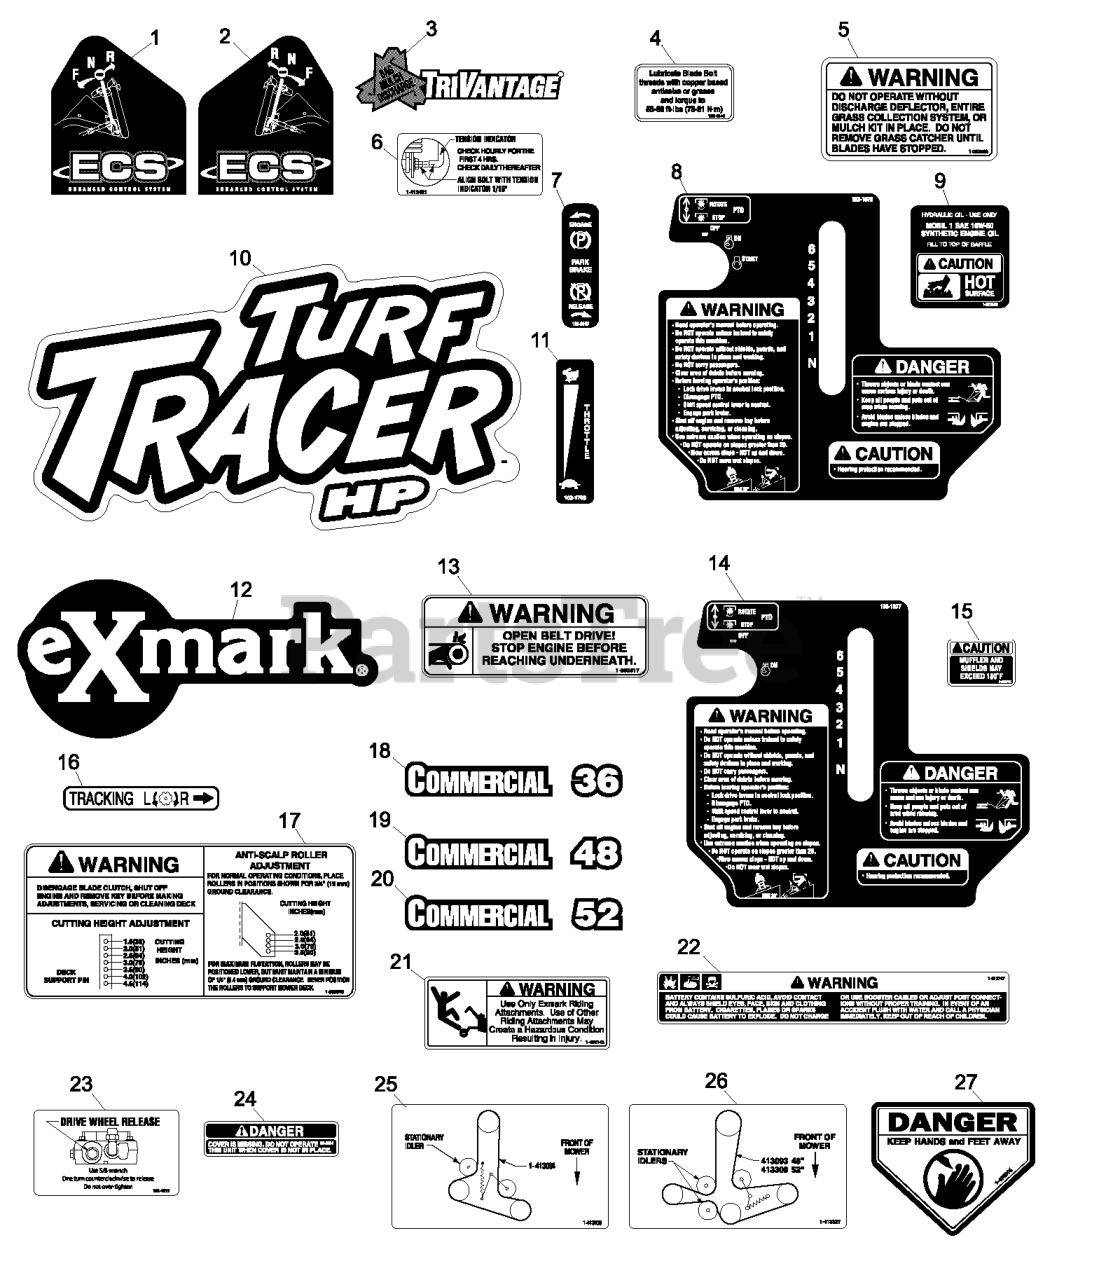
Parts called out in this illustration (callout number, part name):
1	DECAL,LH ECS INSTRUCTION
2	DECAL,RH ECS INSTRUCTION
4	DECAL,BOLT TORQUE
5	DECAL-WARNING, DISCHARGE
6	DECAL,INDICATOR
7	DECAL-BRAKE, PARK
8	DECAL,CONSOLE
10	DECAL,TTHP MODEL
11	DECAL,THROTTLE ONLY
12	DECAL,EXMARK LOGO
13	DECAL,BELT DRIVE
14	DECAL,ECS CONSOLE
16	DECAL,TRACKING ADJUST
17	DECAL,ANTI SCALP
18	DECAL,COMMERCIAL 36
19	DECAL,COMMERCIAL 48
20	DECAL,COMMERCIAL 52
21	DECAL,SULKY WARNING
22	DECAL-BATTERY
23	DECAL,DRIVE RELEASE
24	DECAL-COVER, MISSING
25	DECAL,BELT ROUTING
26	DECAL,BELT ROUTING
27	DECAL-DANGER
